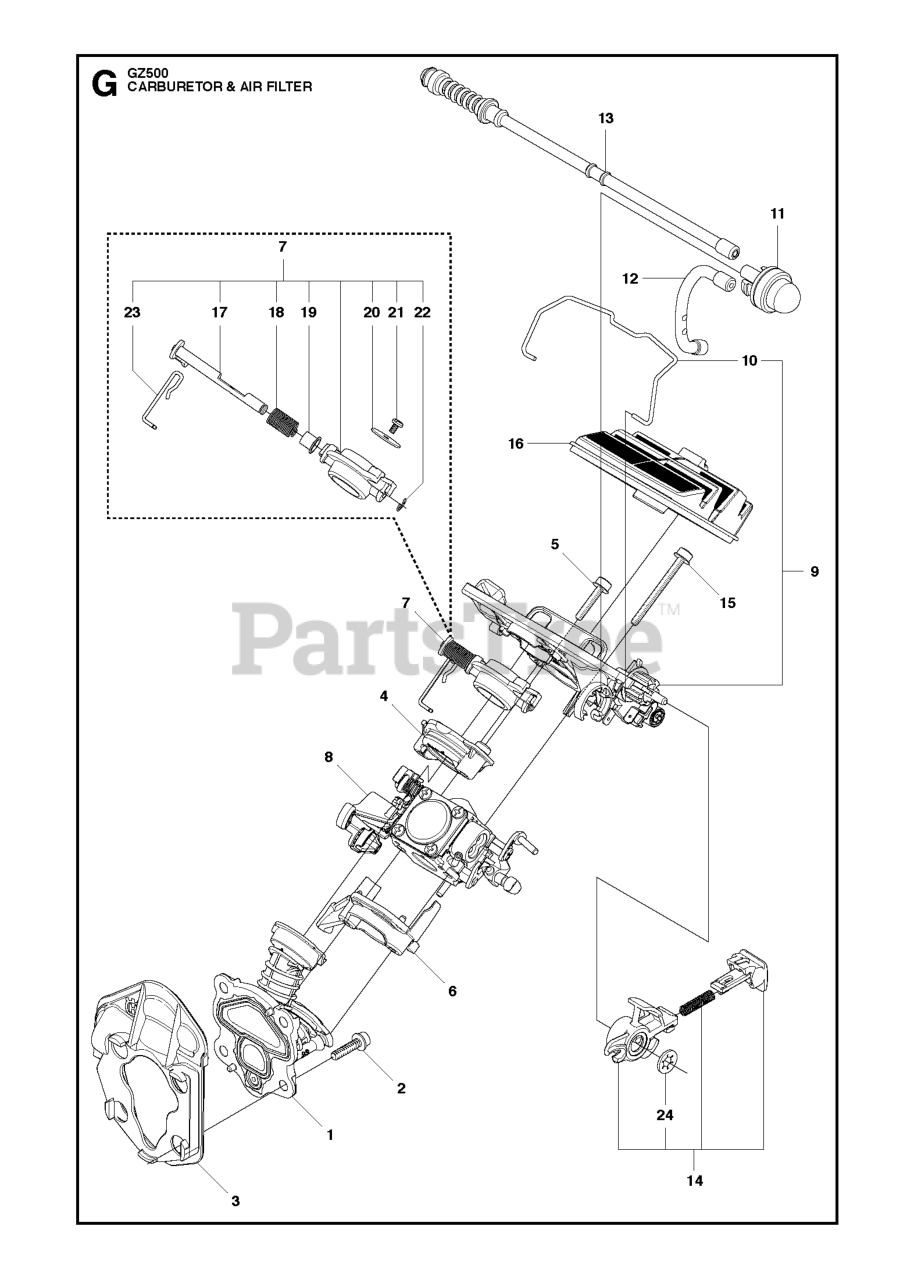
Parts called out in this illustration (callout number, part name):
1	INLET PIPE ASSY
3	INTERMEDIATE WALL
7	THROTTLE
8	CARBURETOR
9	FILTER HOLDER ASSY
11	AIR PURGE BUBBLE
13	RETURN HOSE
16	AIR FILTER - NYLON (80)
16	AIR FILTER - NYLON (44)
16	AIR FILTER - FELT
17	SHAFT ASSY
24	LOCK WASHER
